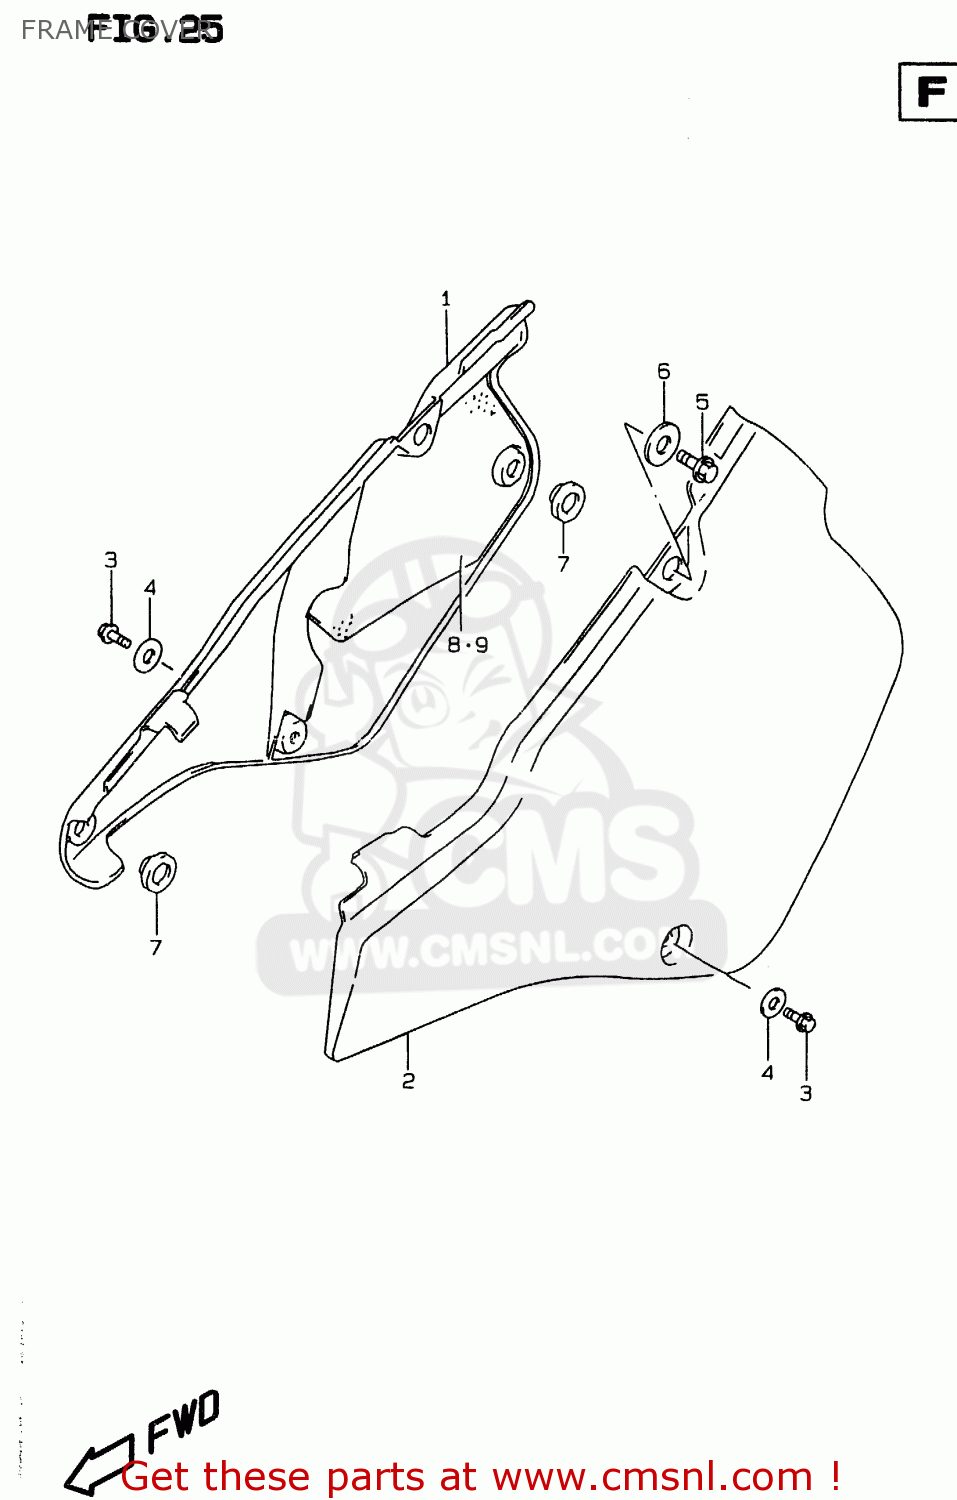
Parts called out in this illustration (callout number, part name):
1	COVER,FRAME,R(WHITE)
2	COVER,FRAME,L(WHITE)
3	BOLT
4	GASKET(6.5X20X1.5) (NAS)
5	BOLT
6	WASHER
7	CUSHION
8	HEATSHIELD,FRAME COVER,R
9	SHIELD,FRAME COVER,RIGHT
